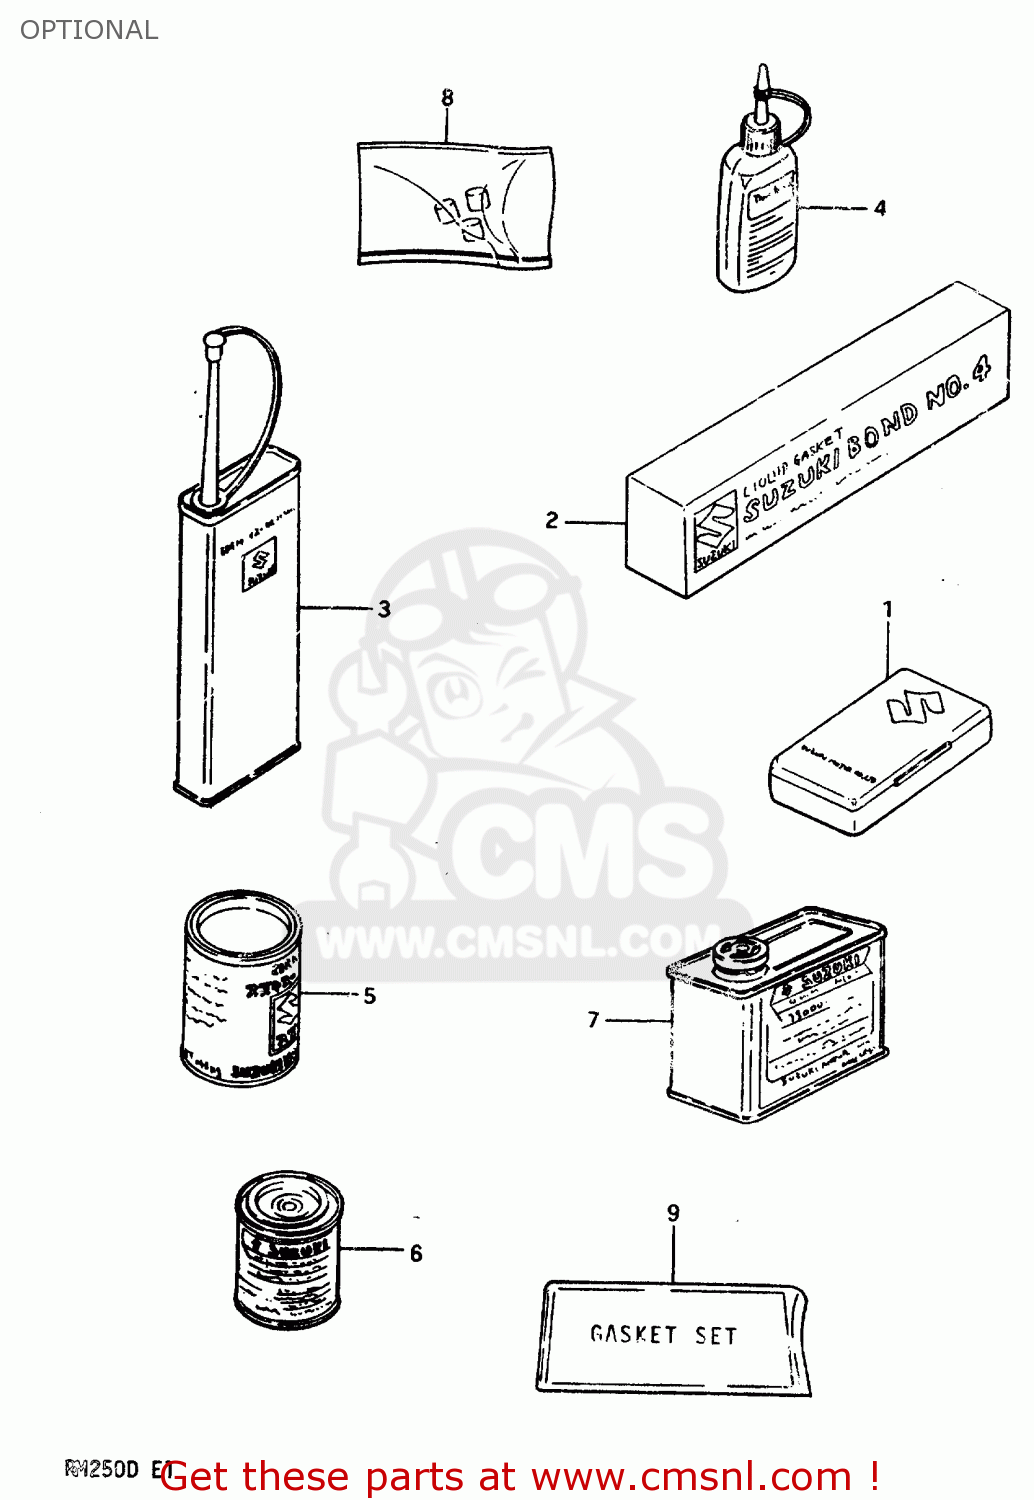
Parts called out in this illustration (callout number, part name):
1	TUBE REPARING TOOL
2	LIQUID GASKET 1
3	THREAD LOCK NO.1401 CLEAR 200G
4	THREAD LOCK NO
5	GREASE(C)EP2 LITHIUM 150G
6	PAINT,BLACK
7	LEAK END
8	GASKET
